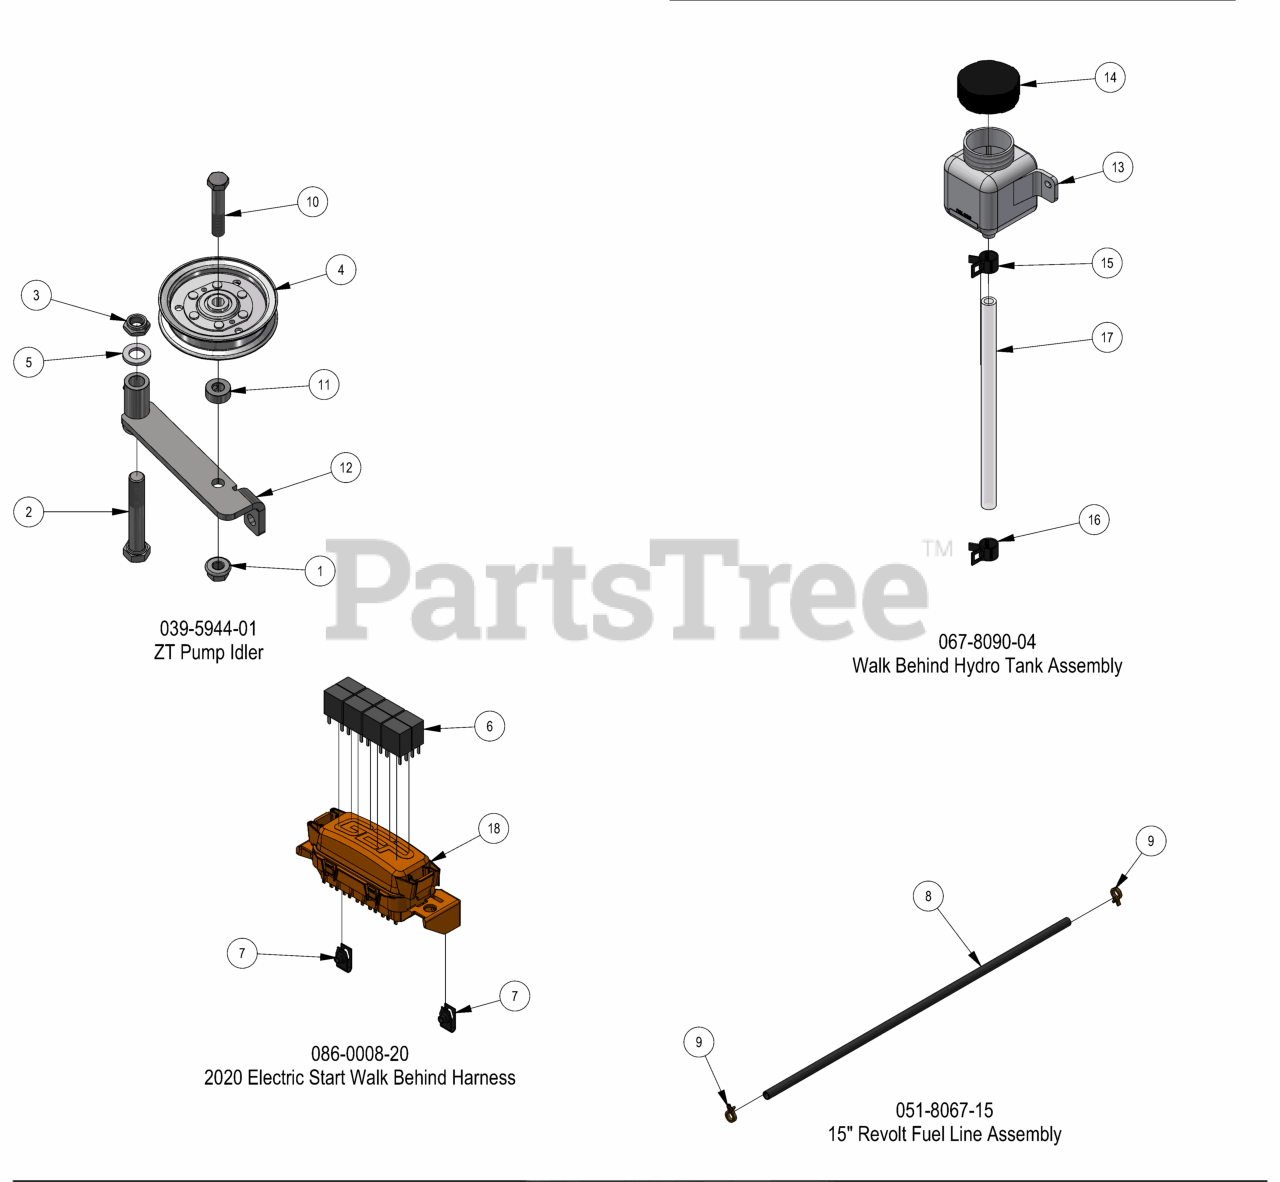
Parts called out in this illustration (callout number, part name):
1	1/2-13 NYLON INSERT FLANGE LOCKNUT ZINC
2	5/8-11 X 4 HEX CAP SCREW (GR.8) ZINC YELLOW
3	5/8-11 NYLON INSERT JAM LOCKNUT ZINC
4	4 3/4" Idler Pulley
5	.635 ID X 1.120 OD X .140 THICK FLAT WASHER NYLON
7	1/4-20 Cage Nut
8	1/4" Fuel Line Hose
9	1/4 Fuel Hose Clamp
10	1/2-13 X 2-3/4 HEX CAP SCREW (GR.5) ZINC
11	1/2 SOLID SHAFT COLLAR (W/1 SET SCREW) ZINC
12	Pump Idler Bracket
13	350ml Expansion Tank
14	Hydraulic Tank Cap
15	3/8" Hose Clamp
16	1/2 Hose Clamp
17	3/8" Clear Hose
18	2020 Electric Start Walk Behind Harness
